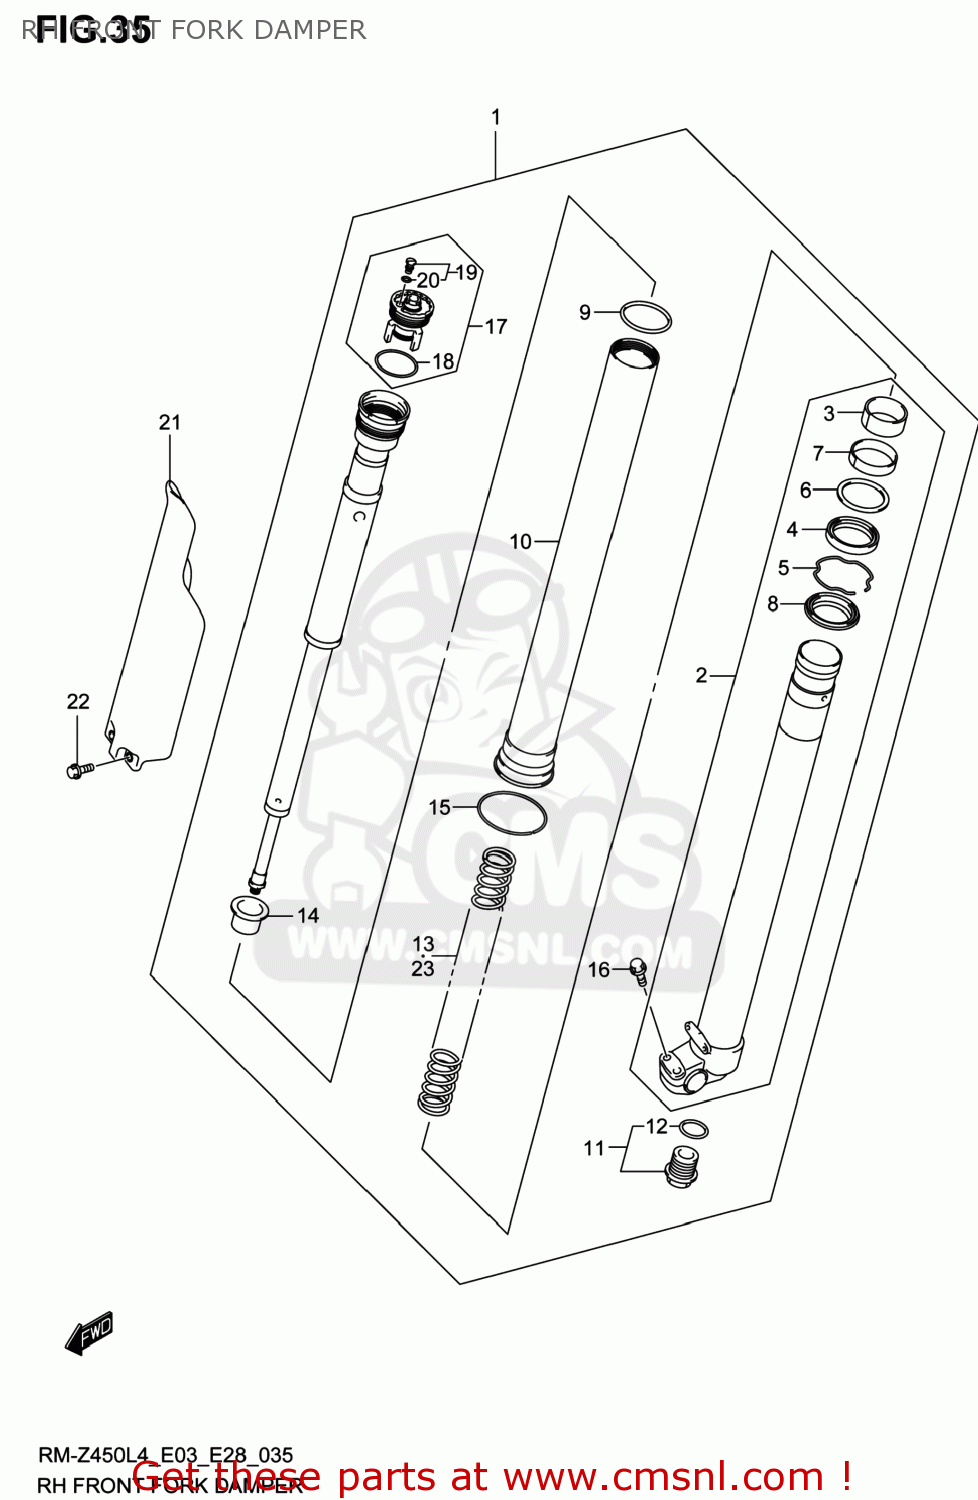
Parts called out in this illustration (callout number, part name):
1	DAMPER ASSY,FR FORK,R
2	TUBE,INNER,R
3	BUSH,SLIDE
4	SEAL,OIL
5	RING,OIL SEAL STOPPER
6	SPACER,SEAL
7	BUSH,GUIDE
8	SEAL,DUST
9	O RING
10	TUBE,OUTER
11	BOLT,CTR
12	O RING
13	SPRING,FR(K=9.8)
14	GUIDE,SPRING
15	STOPPER,RING
16	BOLT
17	BOLT,ADJUSTER
18	O RING,FORK BOLT
19	BOLT,PLUG
20	O RING,PLUG
21	PROTECTOR,FR FORK,R
22	BOLT(6X10)
23	SPRING,FR(K=9.4)
